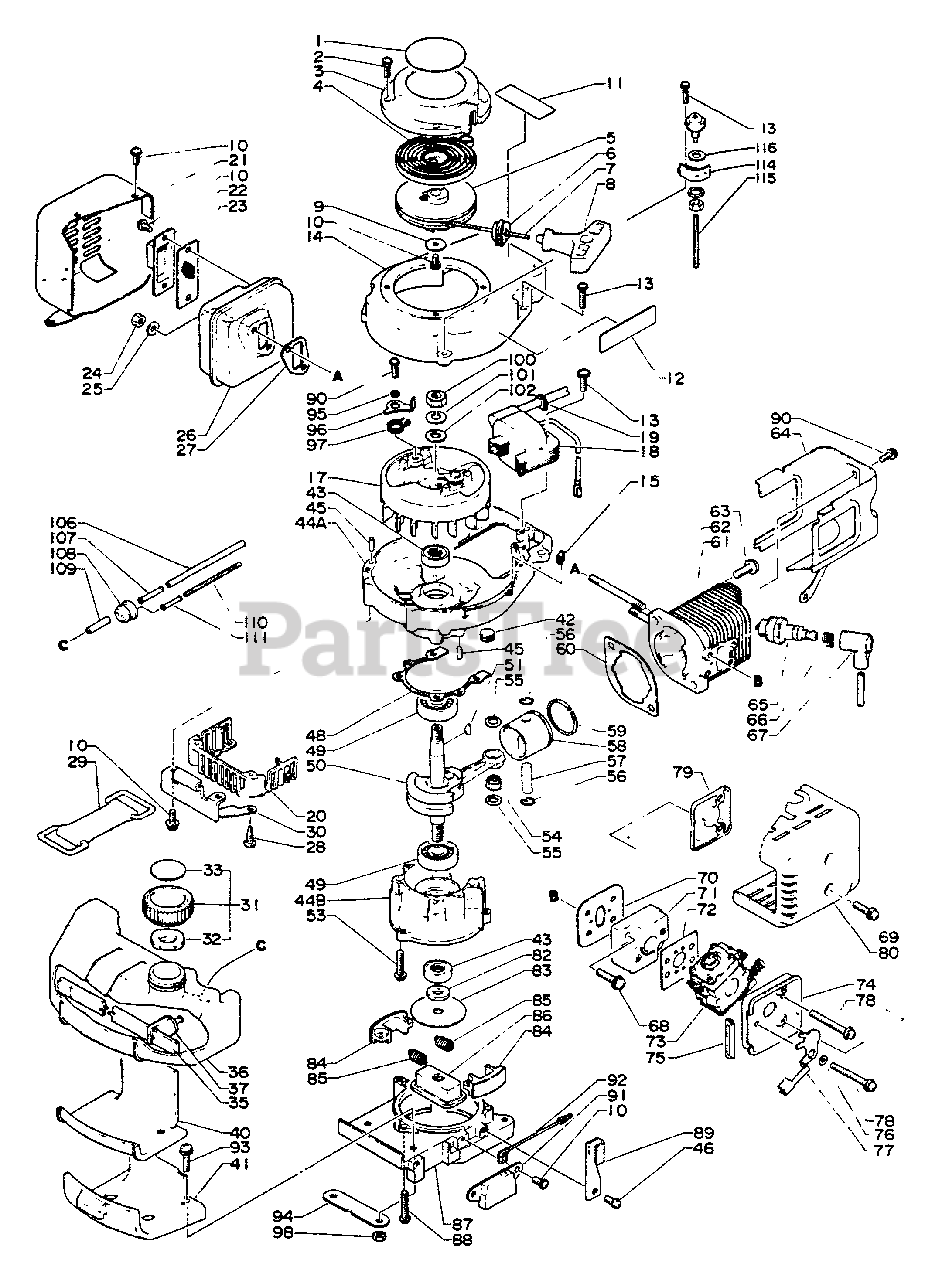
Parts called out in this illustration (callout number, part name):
1	LABEL - ECHO
2	SCREW 4×14
3	CASE, STARTER
4	SPRING, RECOIL
5	REEL, ROPE
6	GUIDE, ROPE
7	ROPE, STARTER 3.0×850
8	GRIP, STARTER
9	WASHER 4.1×15.5×1T
10	SCREW 4×10
11	LABEL
12	LABEL - CAUTION
13	SCREW 4×20
14	CASE, FAN
17	FLYWHEEL
18	COIL, IGNITION
20	SEAL, DUST
21	COVER, MUFFLER
21	MUFFLER
22	SCREEN HOLDER
23	SCREEN, SPARK ARRESTER
24	LOCKNUT - 5
25	WASHER, FLAT 5.5×10×0.8
26	MUFFLER
27	GASKET, EXHAUST
28	SCREW 4×14
29	STRAP
30	BRACKET, FUEL TANK
31	CAP ASSY
32	VALVE, CHECK
33	LABEL - FUEL MIX
35	SEAL, FELT
36	TANK, FUEL
37	FILTER, FUEL
40	CUSHION, FUEL TANK
41	BRACKET, FUEL TANK
42	PLUG
43	SEAL, OIL 12
44	CRANKCASE KIT
44A	CRANKCASE KIT
44B	CRANKCASE KIT
45	PIN, LOCATING 4
46	SCREW 5×14
48	GASKET, CRANKCASE
49	BEARING, BALL - 6201 C3
50	CRANKSHAFT ASSY
53	SCREW 5×30
54	BEARING, NEEDLE
55	WASHER, THRUST
56	RING, SNAP
57	PIN, PISTON
58	PISTON
59	RING, PISTON
60	GASKET, CYLINDER
61	CYLINDER
62	BOLT, STUD
63	SCREW 6×20
64	SHIELD, CYLINDER
65	SPARK PLUG - BM6A
66	TERMINAL, SPARK PLUG CAP
67	CAP, SPARK PLUG
68	SCREW 5×20
69	SCREW 4×18
70	GASKET, INTAKE
71	INSULATOR
72	GASKET, INTAKE
73	CARBURETOR
74	CASE, AIR FILTER
76	WASHER 5.2×8×0.8T
77	SHUTTER, CHOKE
78	SCREW 5×40
79	FILTER, AIR
80	COVER, AIR FILTER
83	PLATE, CLUTCH
84	SHOE, CLUTCH
85	SPRING, CLUTCH
86	HUB, CLUTCH
87	HOUSING, CLUTCH
88	BOLT 4×25
89	CLIP
90	SCREW 5×10
91	COIL, IGNITION
92	LEAD
93	SCREW 5×25
94	WASHER
95	SPACER 5.2×8×2.1
96	RATCHET
98	NUT M5
101	WASHER, SPRING 8
102	WASHER 8.5×16×1.2
106	PIPE, FUEL 3×6×120 BLACK
107	CONNECTOR, PIPE
108	GROMMET
109	PIPE, FUEL
110	PIPE, FUEL
111	CONNECTOR, PIPE
114	BRACKET, PUMP
115	PIPE, FUEL PUMP
116	WASHER 10.5×18×1.6
117	RETAINER, PIPE
